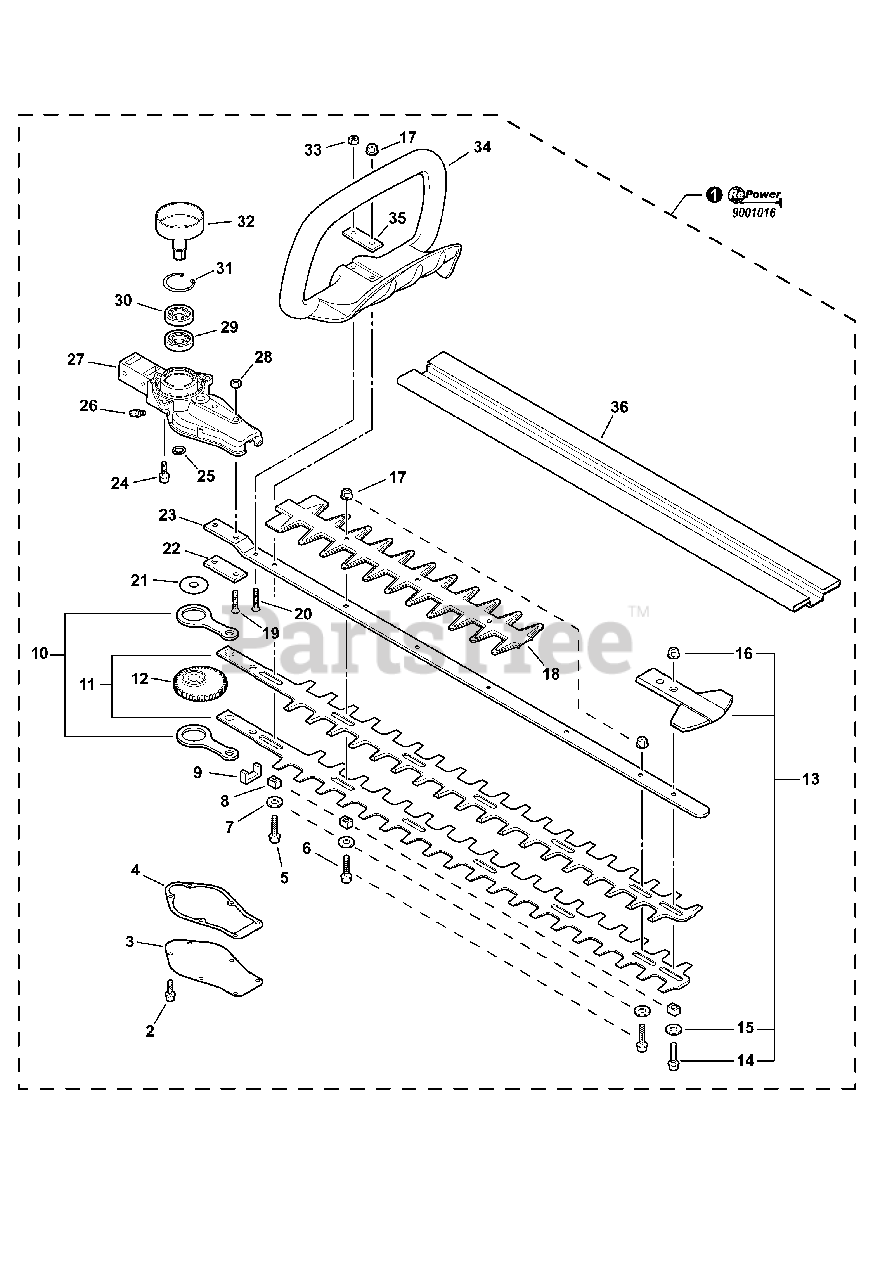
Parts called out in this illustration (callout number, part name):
1	RePower GEAR CASE/BLADES KIT
2	SCREW - 4×10
3	LID, GEAR CASE
4	GASKET, GEAR CASE
5	SCREW - 5×40
6	SCREW - 5×20
7	GUIDE, BLADE
8	WASHER - 6
9	SEAL, FELT
10	ROD, CONNECTING
11	BLADE, TRIMMER - 24"
12	GEAR - DRIVE
13	TIP GUARD KIT
14	SCREW - 5×20
15	WASHER - 6
16	LOCKNUT - 5
17	LOCKNUT - 5
18	PROTECTOR, BLADE
19	SCREW - 6×25
20	SCREW - 5X30
23	SUPPORT, BLADE
24	SCREW - 5×20
25	RING, RETAINING - 14
26	FITTING, GREASE
27	CASE, GEAR
28	LOCKNUT - 6
29	BEARING, BALL - 6202
30	BEARING, BALL - 6202
31	RING, RETAINING - 35
32	DRUM, CLUTCH
33	LOCKNUT - 5
34	HANDLE - FRONT
36	COVER, BLADE - 24" (60cm)
